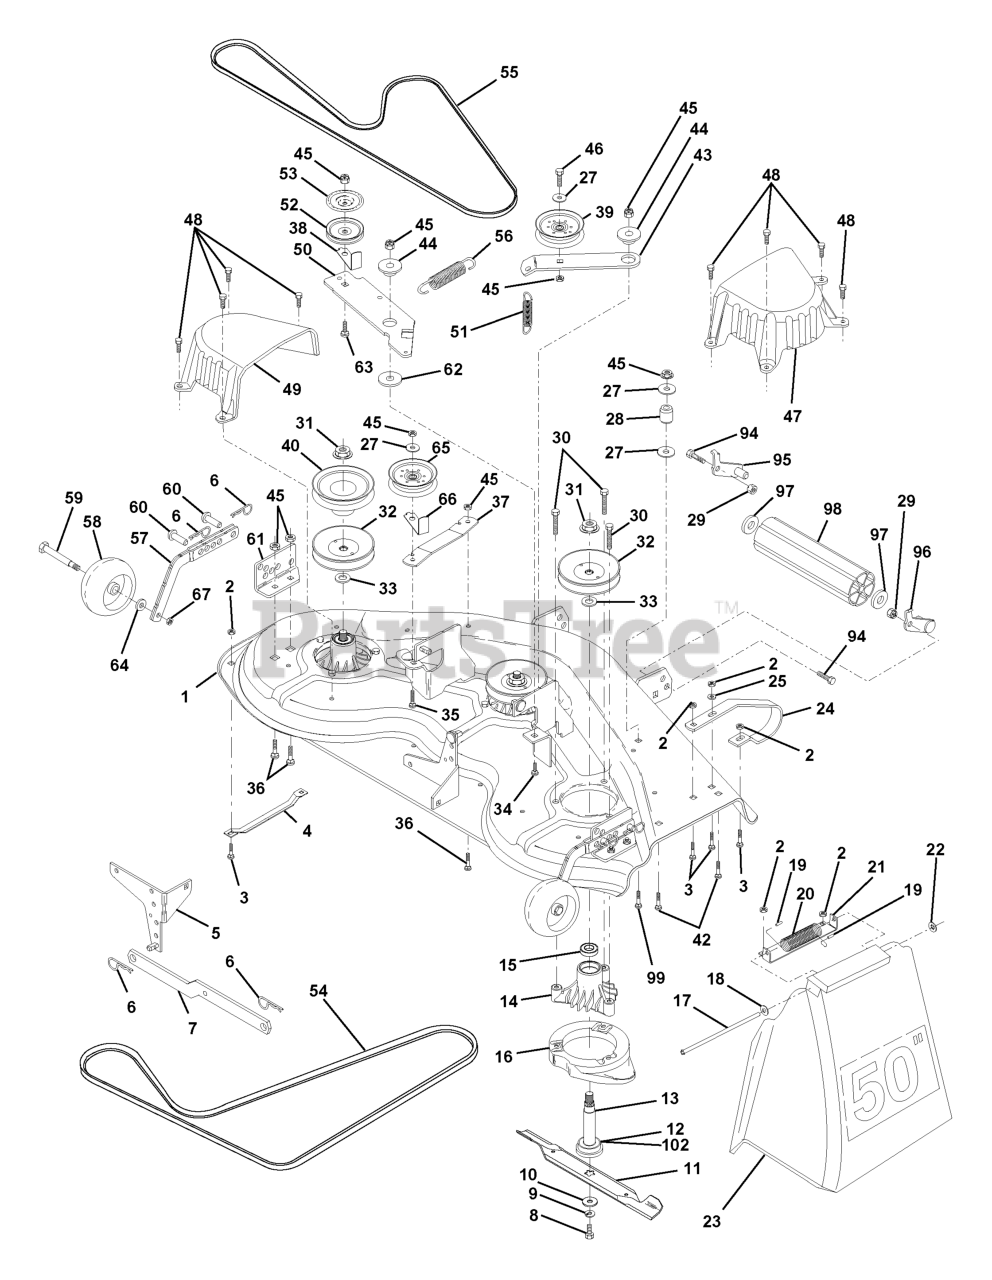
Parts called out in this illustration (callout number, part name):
1	DECK ASM MWR 50VT
2	LOCKNUT
3	BOLT.CARR.SQNK.5/16-18UNC.X3/4
4	RUNNER-LH M
5	BRACKET SWAY BAR
6	RETAINER-SPRNG RB
7	REAR SUSP ARM
8	BLADE BOLT
9	LOCKWASHER
10	WASHER.BLADE
11	BLADE.50".HI-LIFT
12	BEARING.BALL.#6204.(MANDREL)
13	SHAFT.ASM.W/BEARING
14	HOUSING.MANDREL.44/46" VENT
16	STRIPPER
17	ROD-HINGE T
18	Washer 11/32 x 5/8 x 16 Ga.
19	CAP-SLEEVE LT
20	SPRING TORSION
21	BRACKET, DEFLECTOR
22	NUT PUSH M
23	SHIELD.DEFLECTOR.MOWER.50"BLK.
25	WASHER M
27	WASHER
28	IDLER SPRING SPACER
29	NUT
30	SCREW
31	NUT
32	PULLEY/MANDREL
33	WASHER
34	BOLT.3/8-14X1.25
35	BOLT
36	BOLT D
37	STIFFENER ARM
38	KEEPER
39	FLAT IDLER PULLEY
40	PULLEY.DRIVEN.44"
42	RP BOLT 5/16-18 X3/4 ZN/YEL GR
43	ARM.IDLER.SEC.44"
44	SPACER RETAINER
46	BOLT
47	COVER MANDRELL
48	SCREW.1/4-20X5/8
49	COVER.MANDREL.LH.44"
50	ARM.IDLER.PRIMARY
51	SPRING.SEC.44"VEN
52	PULLEY IDLER
53	SHIELD IDLER
54	V-BELT.PRMRY 46/50 VENT.BLK BK
55	BELT V SECONDARY
57	BAR.ASM.GUAGE.WHEEL
58	WHEEL GAGE DONUT
59	BOLT, SHOULDER
60	PIN.CLEVIS
61	BRACKET.GUAGE.WHEEL
62	HARDENED WASHER
63	BOLT.3/8-16X1.50
64	WASHER.5/16.FLAT.STE.STD.
65	PULLEY IDLER FLAT
66	KEEPER
67	LOCKNUT
94	BOLT
95	BRACKET LH (A)
96	BRACKET RH (B)
97	Washer 17/32 x 7/8 x 16 Ga.
98	NOSE ROLLER
102	WASHER FELT
